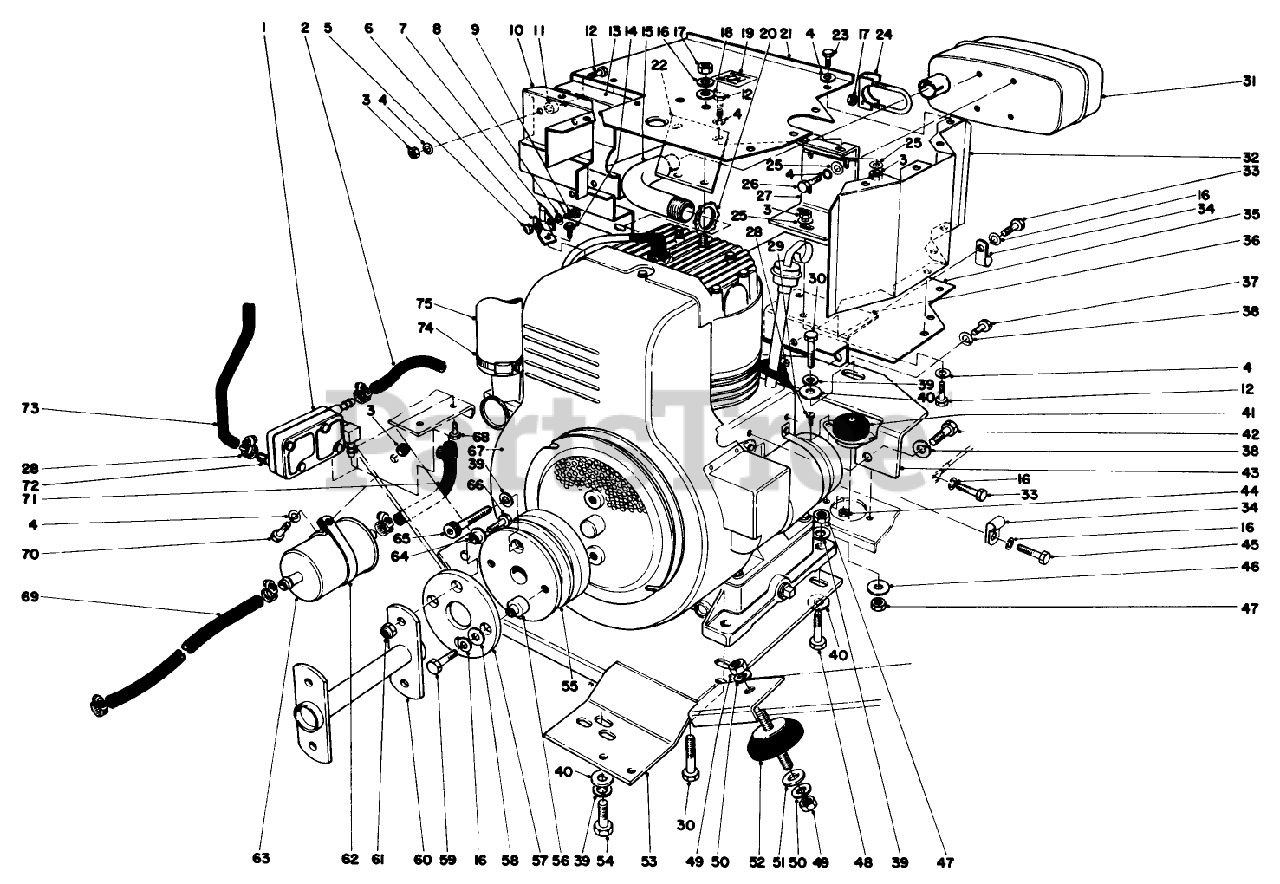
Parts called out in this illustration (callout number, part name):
3	NUT-HEX
4	WASHER-LOCK
5	NUT-HEX
7	CLAMP-BODEN
8	WASHER-LOCK
9	SCREW-PPH
10	REAR SHIELD WA *B
12	SCREW-HH
14	SCREW
15	EXHAUST PIPE
16	Lockwasher
17	NUT-HEX
18	WASHER-PLAIN
23	SCREW THD 1/4 20 5/8
24	MUFFLER CLAMP
25	WASHER-FLAT
26	SCREW-HH
28	CLAMP-HOSE
29	10-24 X 5/8 PAN HD MS
30	SCREW-HH
31	Muffler
32	LH SIDE HT SHIELD *B
33	SCREW-HH
37	SCREW-HH
38	WASHER-LOCK
39	WASHER-LOCK
40	WASHER-FLAT
41	RUBBER MOUNT
43	REAR ENGINE MT *B
44	NUT-LOCK, NI
45	SCREW-HH
46	WASHER
47	NUT-HEX
48	SCREW-HH
49	NUT-HEX
50	WASHER-LOCK
51	WASHER-FLAT
52	RUBBER MOUNT
54	SCREW-HH
55	ENGINE PULLEY *BO
58	WASHER-FLAT
59	SCREW-HH
61	NUT-HEX
65	SCREW-HSH
66	SCREW-HH
67	Engine Briggs Stratton (Model No. 326437)
70	SCREW-HH
71	HOSE-FUEL
74	CLAMP-HOSE
75	AIR CLEANER HOSE
